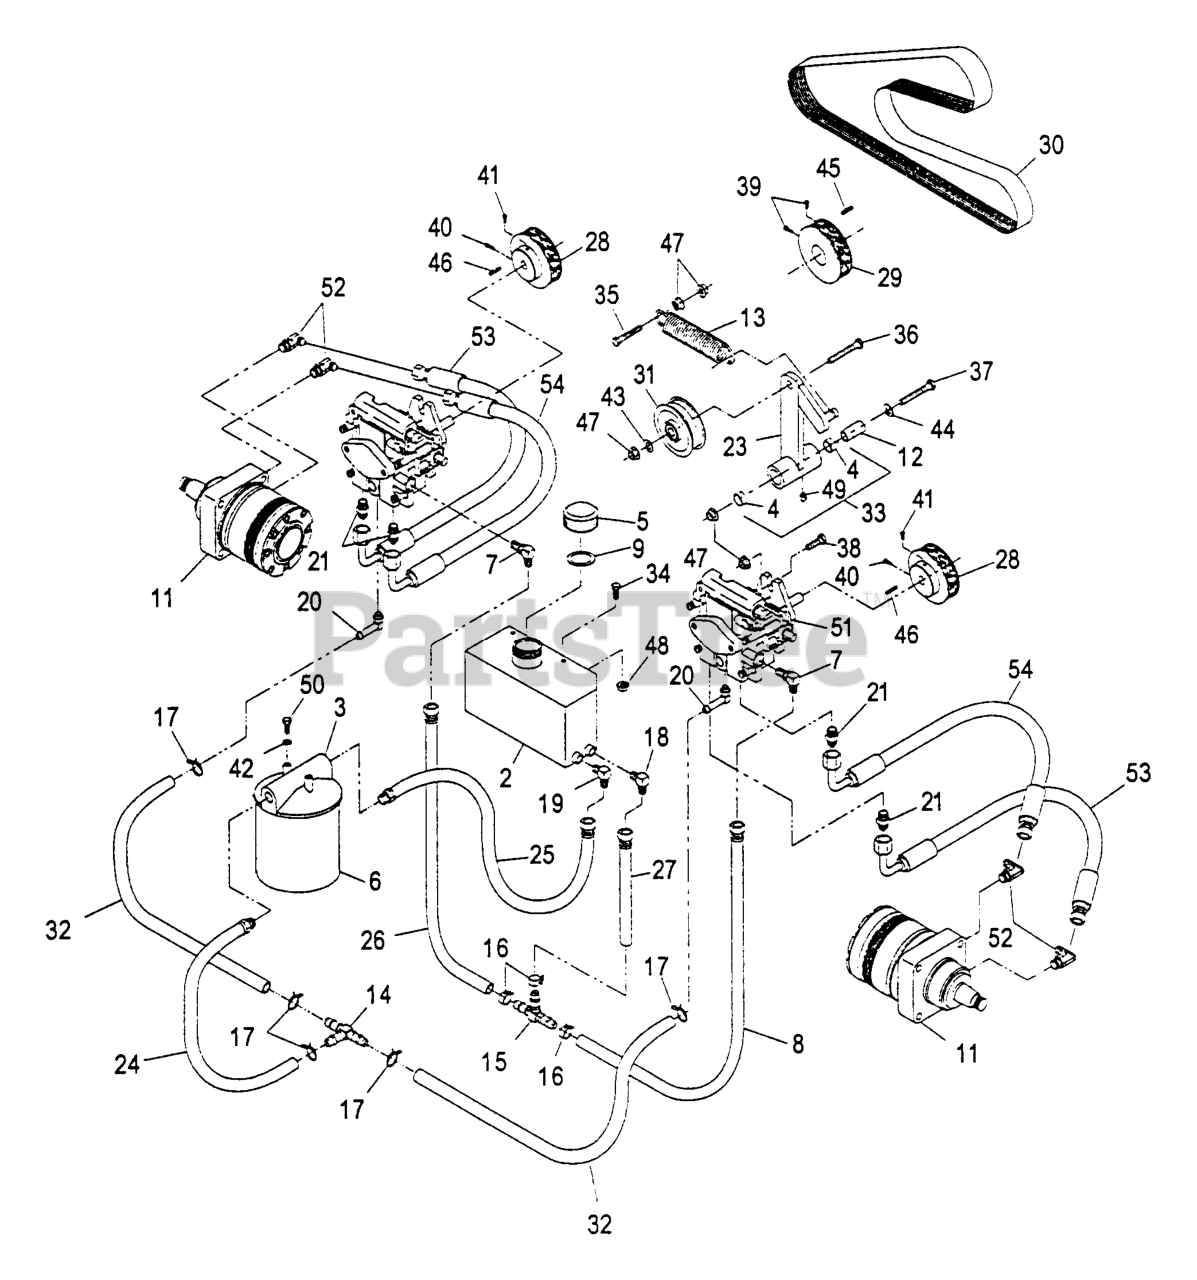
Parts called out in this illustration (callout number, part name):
1	HOSE-PRESSURE, HIGH
3	FILTER-HEAD
4	SLEEVE-BEARING
7	FITTING-90 DEG
8	LOW PRESSURE HOSE ASM
9	GASKET-CAP, TANK
10	FITTING-HYD, 45 DEG
11	MOTOR-WHEEL
12	BUSHING-PIVOT, IDLER
13	SPRING-EXTENSION
14	FITTING-TEE, HOSE
15	FITTING-TEE, HOSE
16	CLAMP-HOSE
17	CLAMP-HOSE
18	FITTING-ELBOW
19	FITTING-ELBOW
20	FITTING
21	FITTING-STRAIGHT
24	HOSE ASM
25	HOSE ASM
26	HOSE ASM
27	HOSE ASM
30	BELT,POLY-V 5K
31	SHEAVE-IDLER
32	HOSE-PRESSURE, LOW
33	BEARING ARM ASM
37	SCREW-HH
39	SCREW-SET
41	SCREW-SET
42	WASHER-LOCK
52	FITTING-90 DEG
53	HOSE-LOWER
54	HOSE-UPPER
